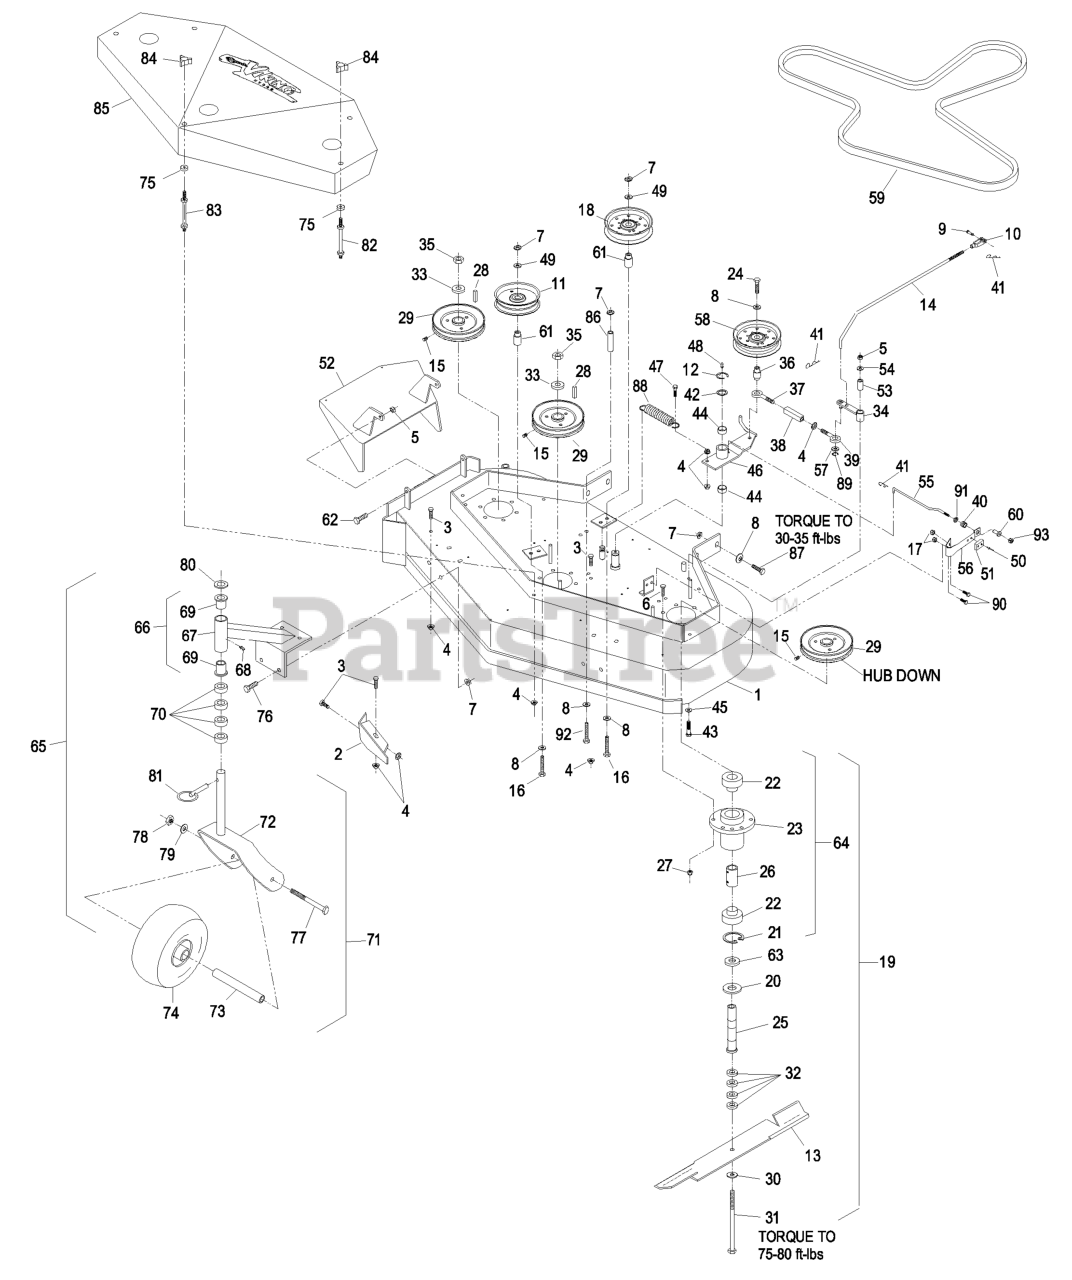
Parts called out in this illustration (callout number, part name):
1	DECK-SERVICE, 48
2	BAFFLE-DOGLEG
9	PIN-CLEVIS
10	YOKE-ADJUSTABLE
11	PULLEY-IDLER
14	ARM-ASSIST, LINKAGE
15	SCREW-SET
19	HOUSING,CUTTER COMPLETE(S
20	GUARD-BEARING, BOTTOM
22	BEARING
25	TUBE-SPINDLE, SHORT
26	SPACER-BEARING
29	SHEAVE
30	WASHER-SPRING
31	SCREW-CAP, HH
33	WASHER-RETAINER, SHEAVE
34	ARM-ASSIST
36	BUSHING-ENGAGEMENT
37	EYEBOLT-THREAD, LH
38	BODY-TURNBUCKLE
39	EYEBOLT-THREAD, RH
40	SPRING-COMPRESSION
41	PIN-COTTER
42	WASHER-SPINDLE
44	SLEEVE-BEARING
45	WASHER-SPRING
46	ENGAGE ARM ASM
51	PAD-BRAKE
53	TUBE-PIVOT
55	ROD-BRAKE
56	PAD AND SPRING ASM
59	BELT,BLADE 48
60	SPACER-FLANGED
63	SPACER-PULLEY/BEARING
65	CASTER/MOUNT ASM
66	SUPPORT ASM
69	BEARING-FLANGED
70	SPACER-CASTER
80	WASHER-FLAT
82	STUD-SHIELD, BELT (SHORT)
83	STUD-SHIELD, BELT (LONG)
84	KNOB-3 PRONG
85	Shield W/Decals 48"
88	SPRING-EXTENSION
91	RING-PUSH ON
